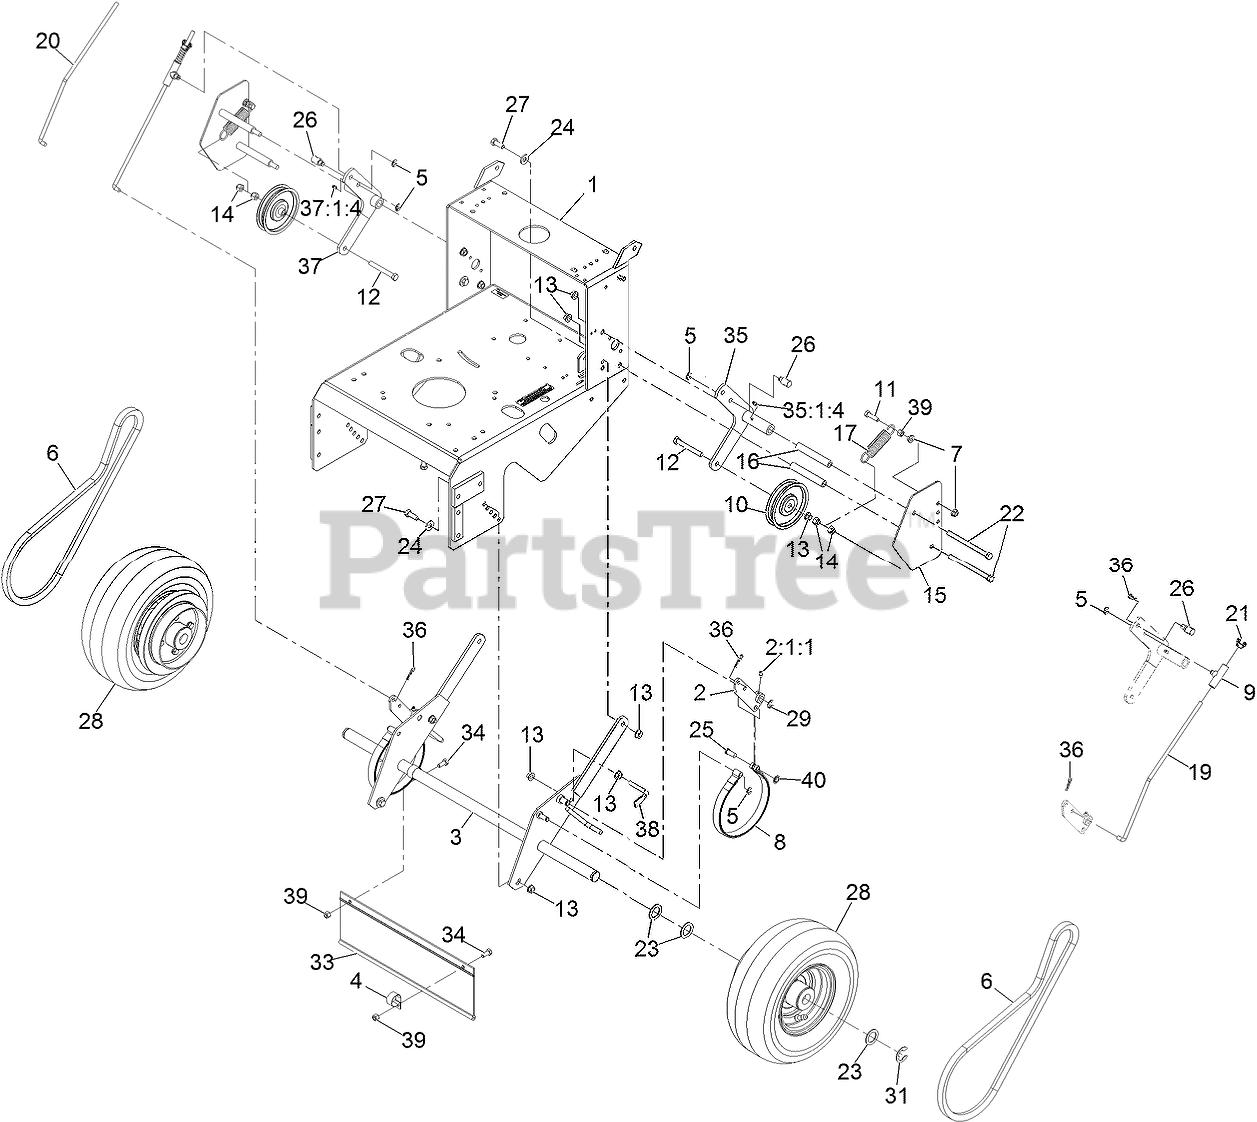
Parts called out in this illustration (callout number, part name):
1	ASM, METRO ENGINE DECK W/
2	ARM-BRAKE
2:1:1	ASM,BUSHING/ZERK
4	CLAMP-R
5	RING-RETAINING
6	BELT,WHEEL DRIVE
8	BAND-BRAKE
9	SWIVEL-BRAKE
10	IDLER-WHEEL, DRIVE
11	SCREW-HH, SPECIAL
12	SCREW-HH
13	NUT-HHF, WHIZ
14	NUT-LOCK, NI
15	SHIELD-WHEEL, DRIVE
16	SPACER-SHIELD
17	SPRING-EXTENSION
19	LINKAGE-BRAKE, LH
20	LINKAGE-BRAKE, RH
21	WINGNUT-NYLOCK
22	SCREW-HH
23	WASHER-SPACER
24	WASHER-BELLEVILLE
25	PIN-CLEVIS
26	SWIVEL-DRIVE LEVER, 3/8 L
27	SCREW-HH
28	DRIVE WHEEL ASM
29	RING-RETAINING, EXTERNAL
31	RING-SNAP
33	SHIELD-TRAILING
34	SCREW-HH
35	ARM-IDLER, LH
35:1:4	FITTING-GREASE
36	PIN-COTTER
37	ARM-IDLER, RH
37:1:4	FITTING-GREASE
38	SCRAPER
39	NUT-LOCK, NI
40	RING-RETAIN,PUSH,EXT,FLAT
